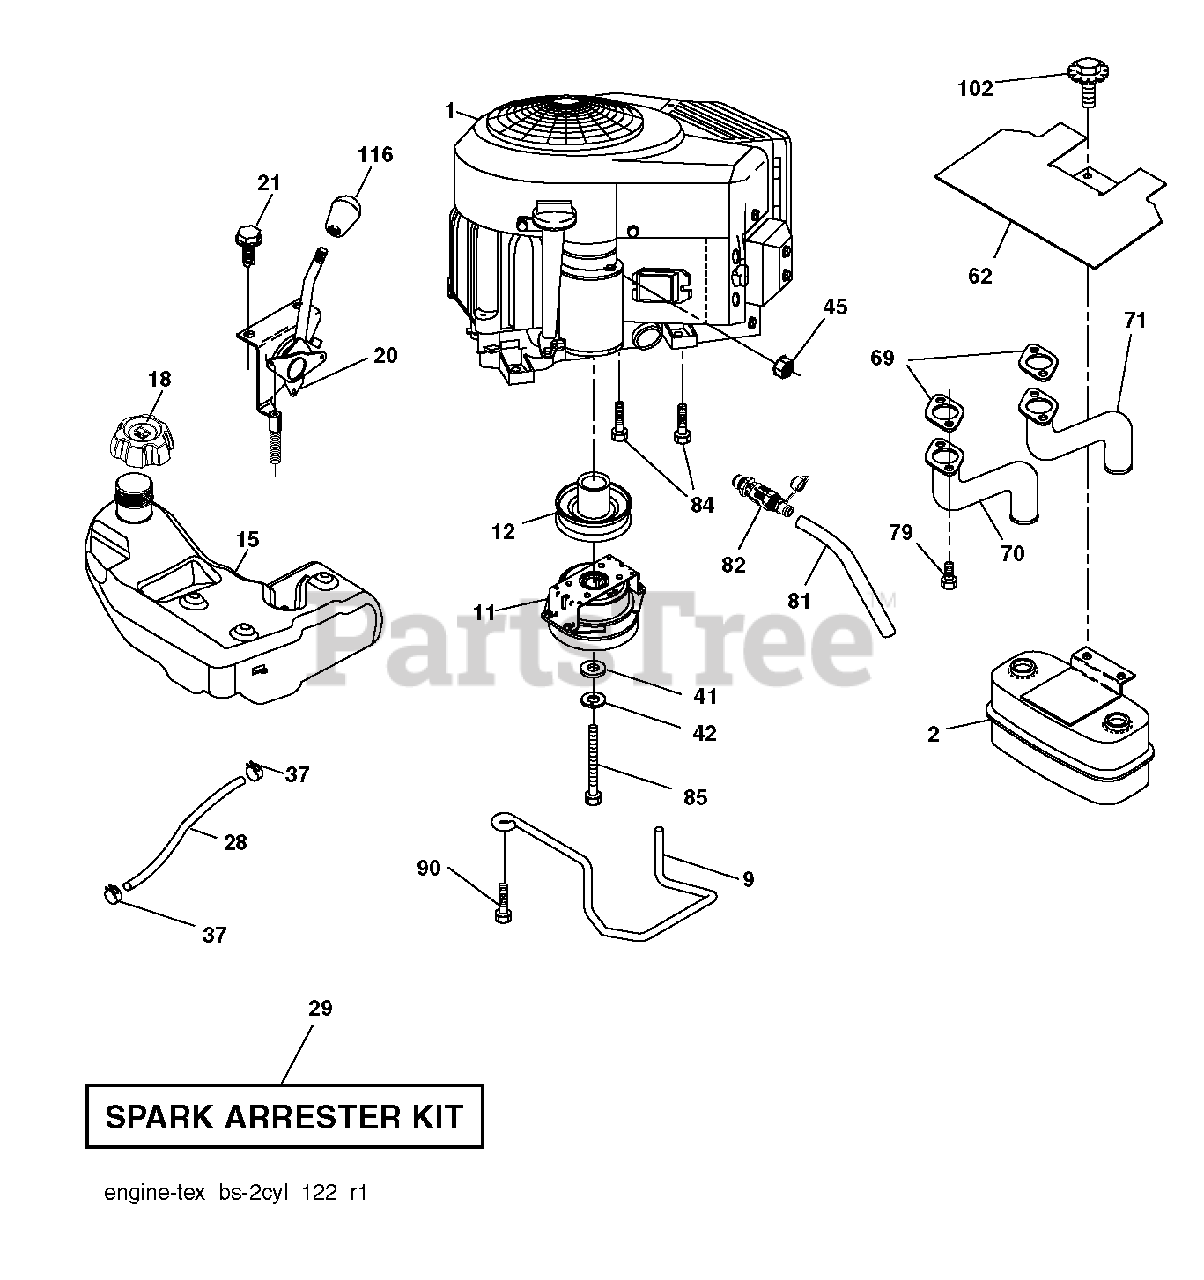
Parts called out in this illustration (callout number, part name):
2	MUFFLER.ASM.TWN.EXTNDED.DFLCTR
9	KEEPER BELT ENGINE
11	CLUTCH.OGURA.5.0PD.GT1.5A-EH07
12	PULLEY.ENGINE.TUFFTORQ
15	TANK.FUEL.4GAL
18	CAP.FL.R.3'N/CARB.H.CROWN.498
20	CONTROL THROTTLE/CHOKE
21	SCREW.#10 X 0.750.BOS
28	REPL BY 532 00 85-43
29	KIT.SPARK ARRESTOR 794945 B&S
37	HOSE CLAMP
42	LOCKWASHER
45	NUT
62	SHIELD.HEAT.MUFFLER
69	GASKET.MUFFLER
70	EXHAUST.TUBE.LH.BS/TWIN
71	EXHAUST.TUBE.RH.B&S.TWIN.INTEK
79	SCREW.SOCKET.HEAD.5/16-18
81	TUBE, DRAIN OIL ASM.
82	VALUE.OIL.DRAIN
84	SCREW.3/8-16
85	BOLT HEX 7/16-20 X 3.75 GR. 5
90	SCREW 3/8-16X1
102	SCREW
116	KNOB - SHIFT
